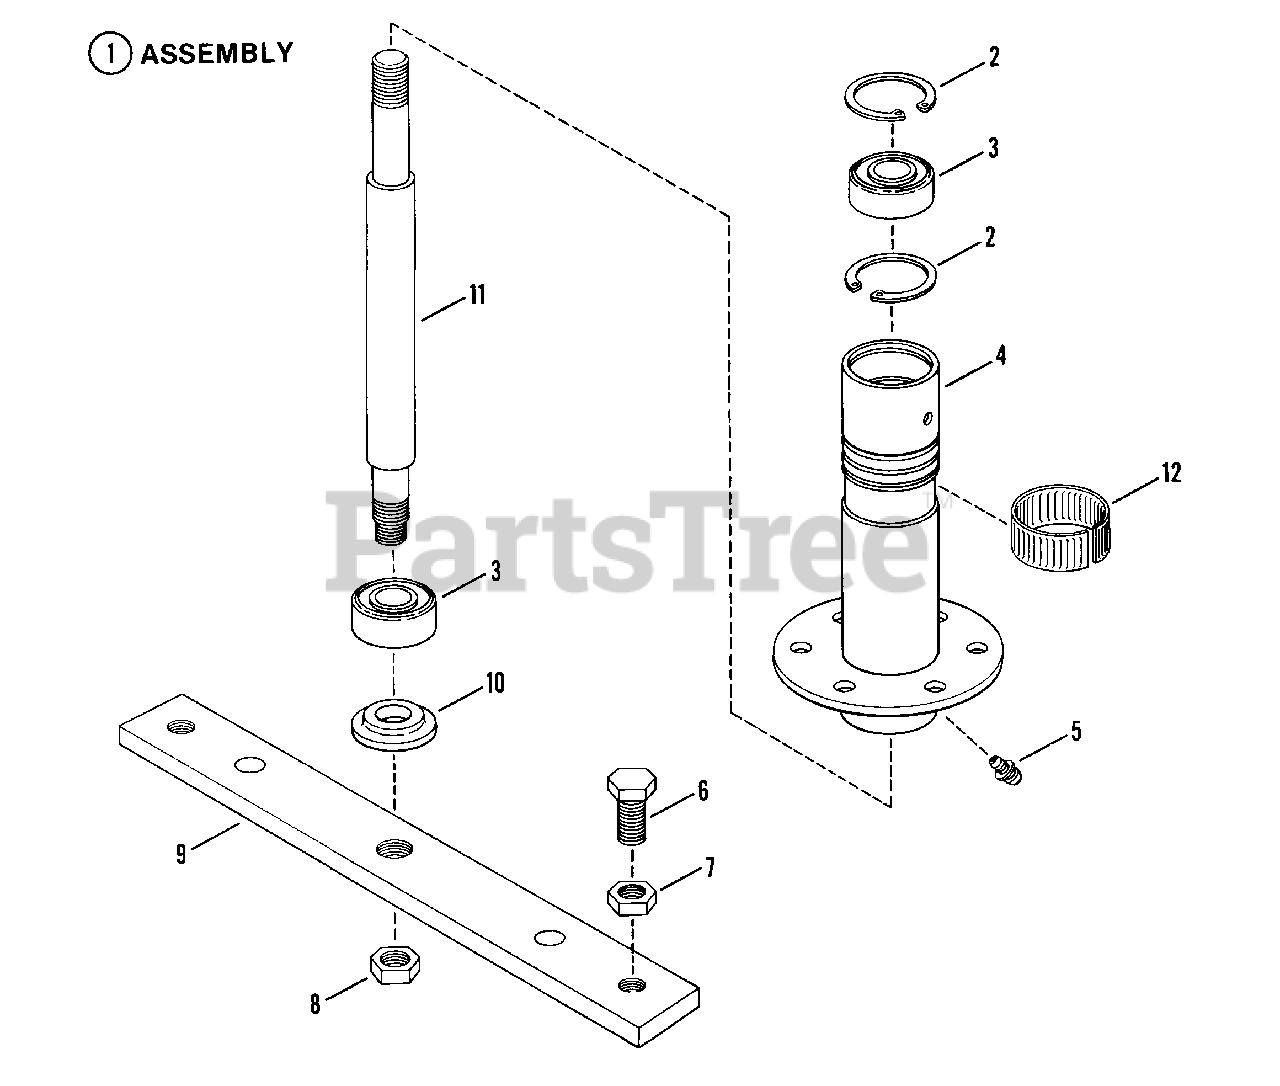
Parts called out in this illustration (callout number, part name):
1	ASSEMBLY, Spindle Housing
2	RING, Retaining
3	BEARING, Spindle
4	HOUSING, Spindle
5	FITTING, Lube (Press fit for .187 hole-no ball)
6	SCREW, 1/2-20x1" Hex Head Cap, Grade 5
7	JAM-NUT, 1/2-20 Hex
8	LOCKNUT, 5/8-18 Hex
9	HOLDER, Blade
10	WASHER, Spindle
11	SPINDLE, Shaft (10.237" Long)
12	RING, Tolerance
